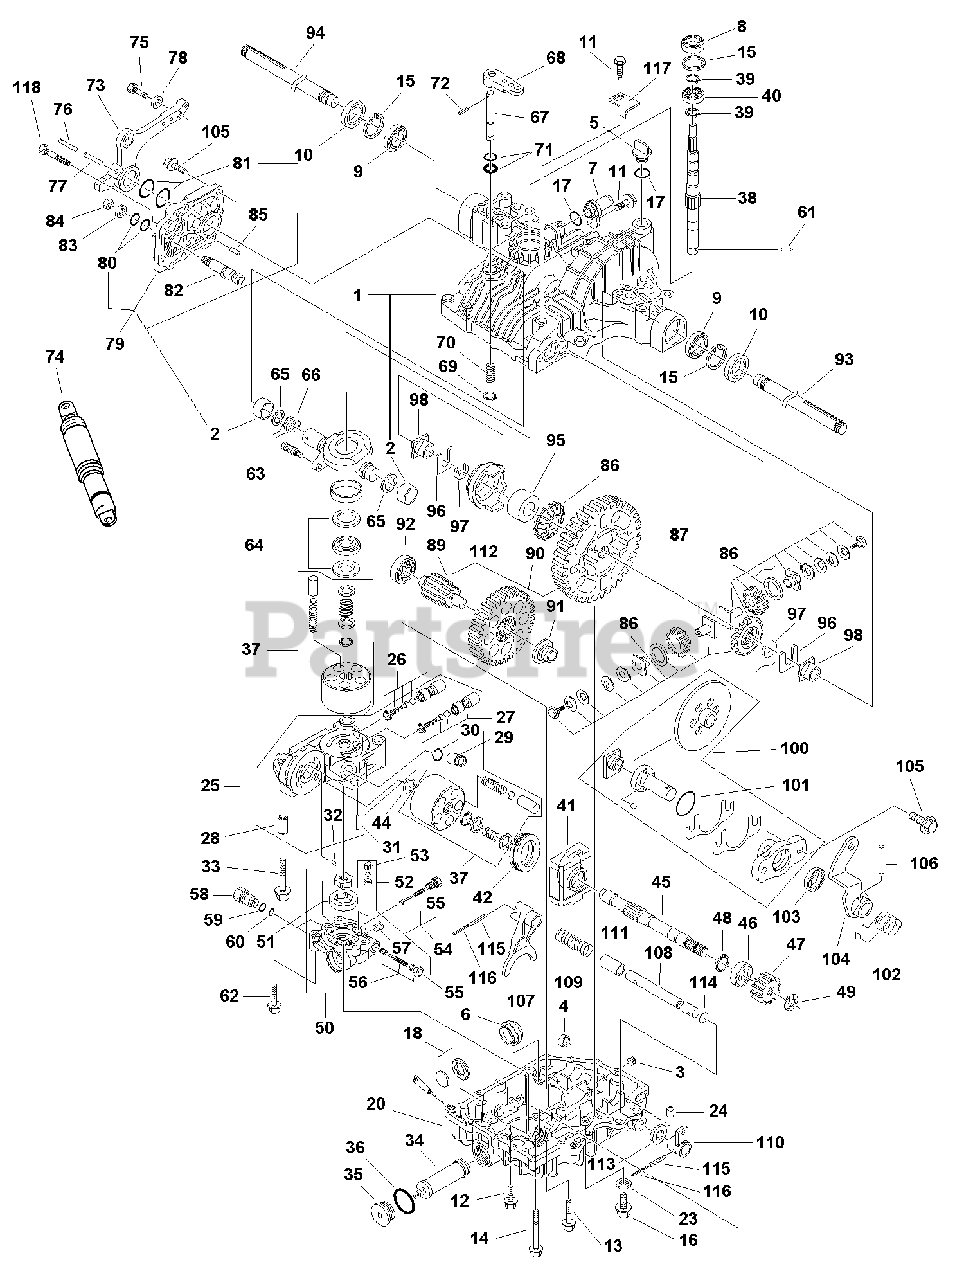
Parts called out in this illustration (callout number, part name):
1	UPPER HOUSING COMPLETE
2	BEARING, 28 x 15
3	TAPER PLUG, 1/8
4	BORE PLUG, 17
5	CAP, Oil, 20
6	FILTER
7	FITTING
8	SEAL
9	BEARING
10	SEAL
11	SCREW, Tapping, 8 x 25
12	SCREW, Tapping, 8 x 30
13	SCREW, Tapping, 8 x 45
14	BOLT, 8 x 75
15	RING, 47
16	BOLT, 10 x 12
17	PACKING, P18
18	MAGNET COMPLETE
20	LOWER HOUSING COMPLETE
23	WASHER, Seal 10
24	PIPE, 13 x 11.3
25	CENTER CASE COMPLETE
26	VALVE, (A-1 SET)
27	VALVE, (A-2 SET)
28	KNOCK PIN, 15.5 x 30
29	PLUG, 16 x 25
30	PACKING
31	PIN, 8 x 14
32	PIN, 3 x 9.8
33	BOLT, 10 x 75
34	FILTER
35	CAP, (M40)
36	PACKING
37	CYLINDER BLOCK COMPLETE
38	PUMP SHAFT
39	RING, 17
40	BEARING, 6303
41	HOUSING
42	BEARING, 51207
44	WASHER, 18 x 31 x 1
45	SHAFT MOTOR
46	BEARING 6004 SH2 U
47	MOTOR GEAR
48	SNAP RING, 20
49	RING, E15
50	PUMP CASE S/A
51	PUMP CASE COMPLETE
52	3RD CHECK COMPLETE
53	HOLDER, (SEAT)
54	VALVE, (IMP COMPLETE)
56	VALVE, (CHARGE COMPLETE)
57	PLUG, PT 1/8
58	CONNECTOR
59	O-RING
60	PACKING, 6.1
61	PIN, 3.2 x 21
62	BOLT, 8 x 45
63	SWASH PLATE COMPLETE
64	BEARING COMPLETE
65	WASHER
66	SPRING (N/C)
67	SHAFT (BYPASS)
68	LEVER (BYPASS)
70	SPRING
71	PACKING
72	PIN, 3.0A*20
73	CONTROL LEVER
74	SHOCK ABSORBER
75	BOLT
76	PIN, 6.0A x 50
77	PIN, 3.5A x 50
78	WASHER, 10
79	SIDE COVER SET
80	PACKING, P14
81	PACKING, P28
82	FULCRUM, (ECCENT)
83	WASHER
84	NUT 12
85	PIN, 8 x 16
86	DIFFERENTIAL GEAR KIT
87	FINAL GEAR
89	SHAFT, (F PINION)
90	REDUCTION GEAR
91	BUSHING, 15
92	BEARING, 6203SH2
93	AXLE SHAFT L
94	AXLE SHAFT R
95	COLLAR, (Diff. Lock)
96	THRUST WASHER
97	RING
98	BUSHING
100	BRAKE KIT
101	PACKING, G35
102	SP, (RETURN)
103	SEAL, TC173007
104	ARM, (BRAKE)
105	BOLT, 8 x 25
106	PIN, 6.0A x 4.0
107	FORK, (Diff. Lock)
108	SHAFT, (Diff. Lock)
109	SPRING, (Diff. Lock)
110	ARM, (Diff. Lock)
111	COLLAR, (STOP)
112	SLIDER, (Diff. Lock)
113	WASHER, 17 x 32 x 3
114	PACKING, 1A P12.5
115	PIN, 6.0A*32
116	PIN, 3.5A x 32
117	STOPPER, Brake
118	SCREW, Tapping 8 x 35
